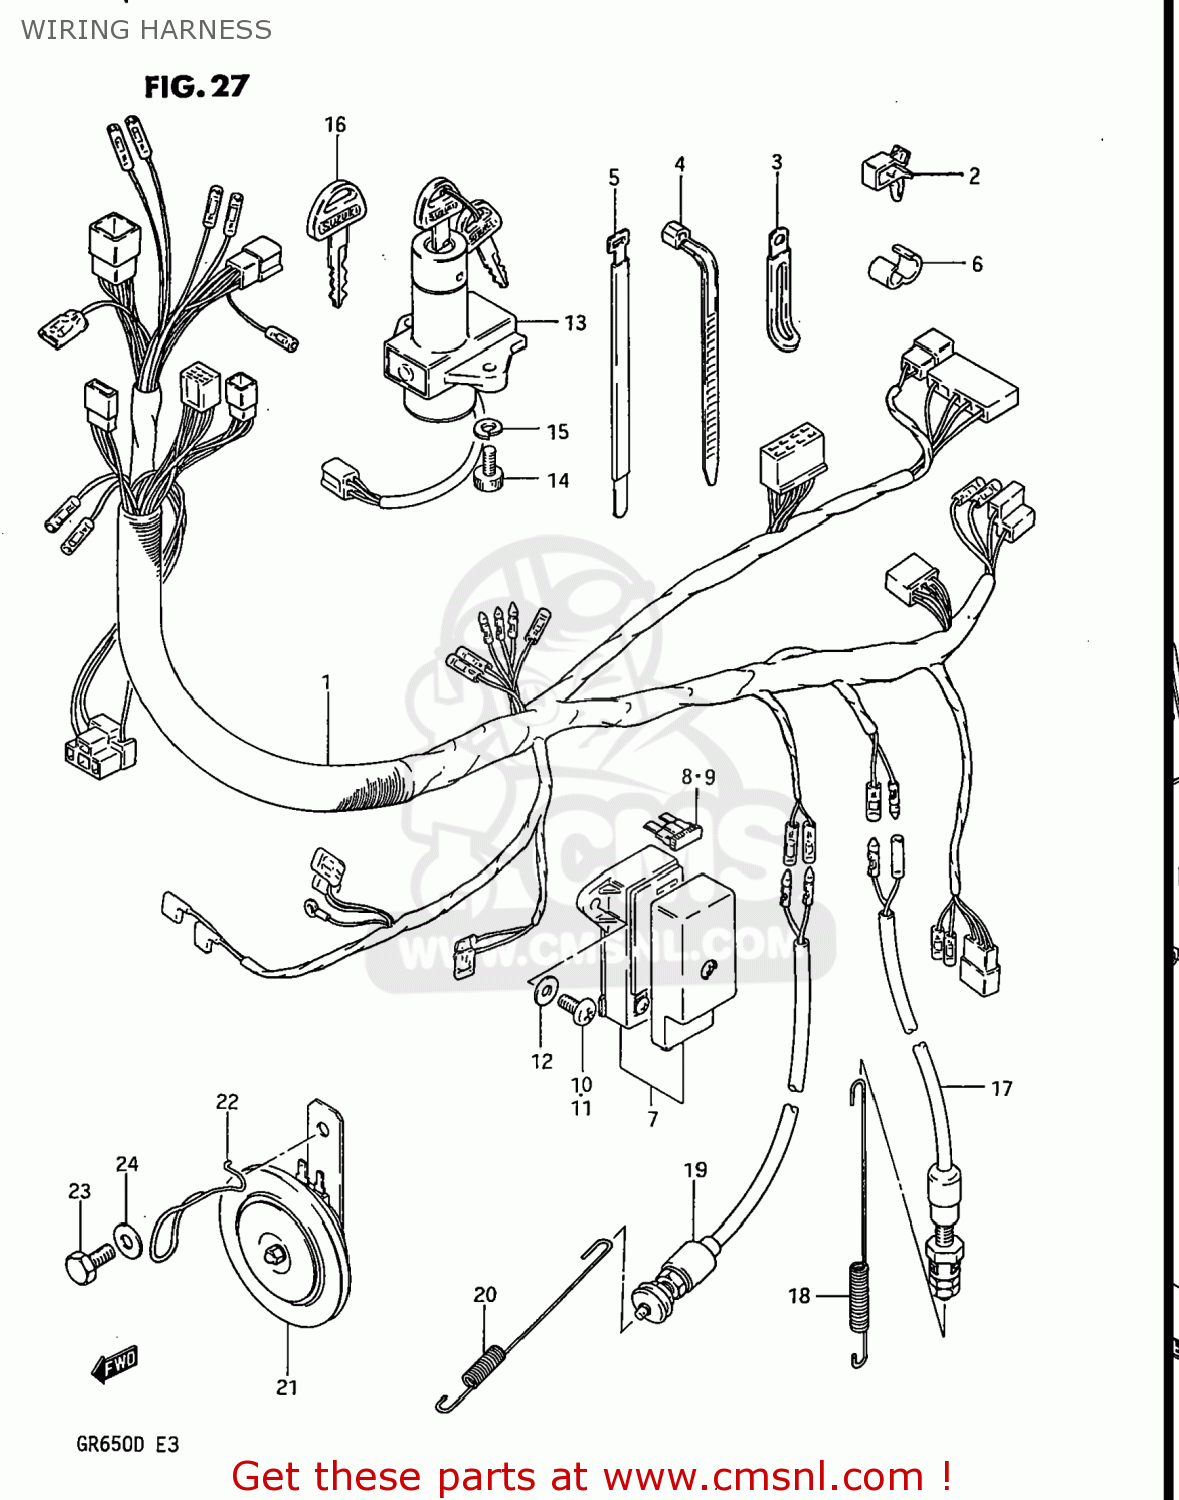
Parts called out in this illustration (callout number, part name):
1	HARNESS,WIRING
2	CLIP
3	CLAMP
4	CLAMP(L:125)
5	CLAMP
6	CLIP
7	BOX ASSEMBLY,FUSE
8	FUSE(10A)
9	FUSE(15A)
10	SCREW 6X12
11	SCREW
12	WASHER
13	SWITCH ASSY,IGNITION
14	BOLT
15	LOCK WASHER
16	KEY,BLANK
17	SWITCH ASSEMBLY,STOP LAMP
18	SPRING
19	SWITCH ASSEMBLY,SIDE STAND
20	SPRING
21	HORN ASSEMBLY
22	PROTECTOR, HORN
23	BOLT
24	WASHER
